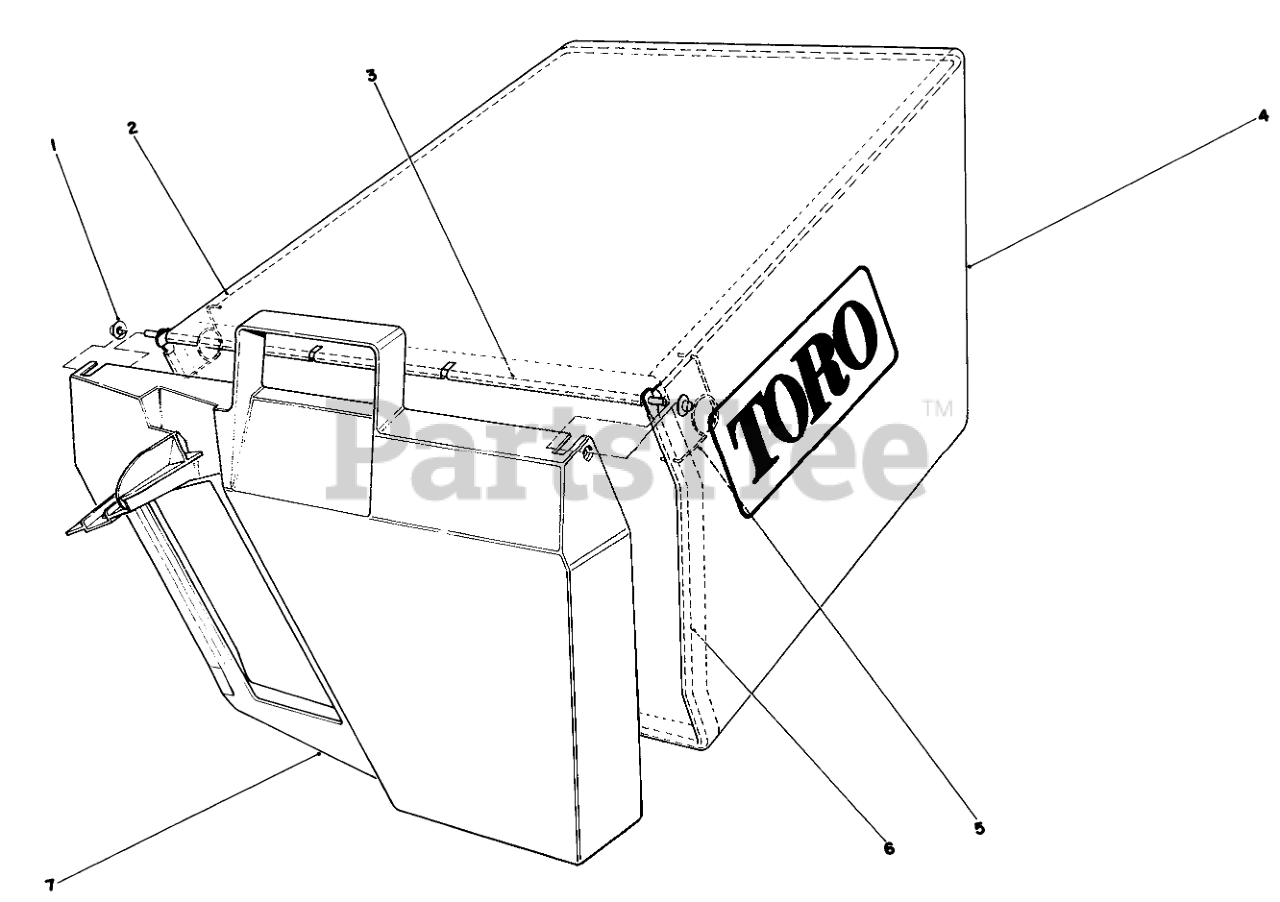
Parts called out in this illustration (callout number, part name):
1	NUT-PUSH
2	FRAME-BAG, UPPER
3	HINGE-DOOR, BAG
4	Bag
5	SPRING
6	BAG FRAME
7	Door Grass Bag
